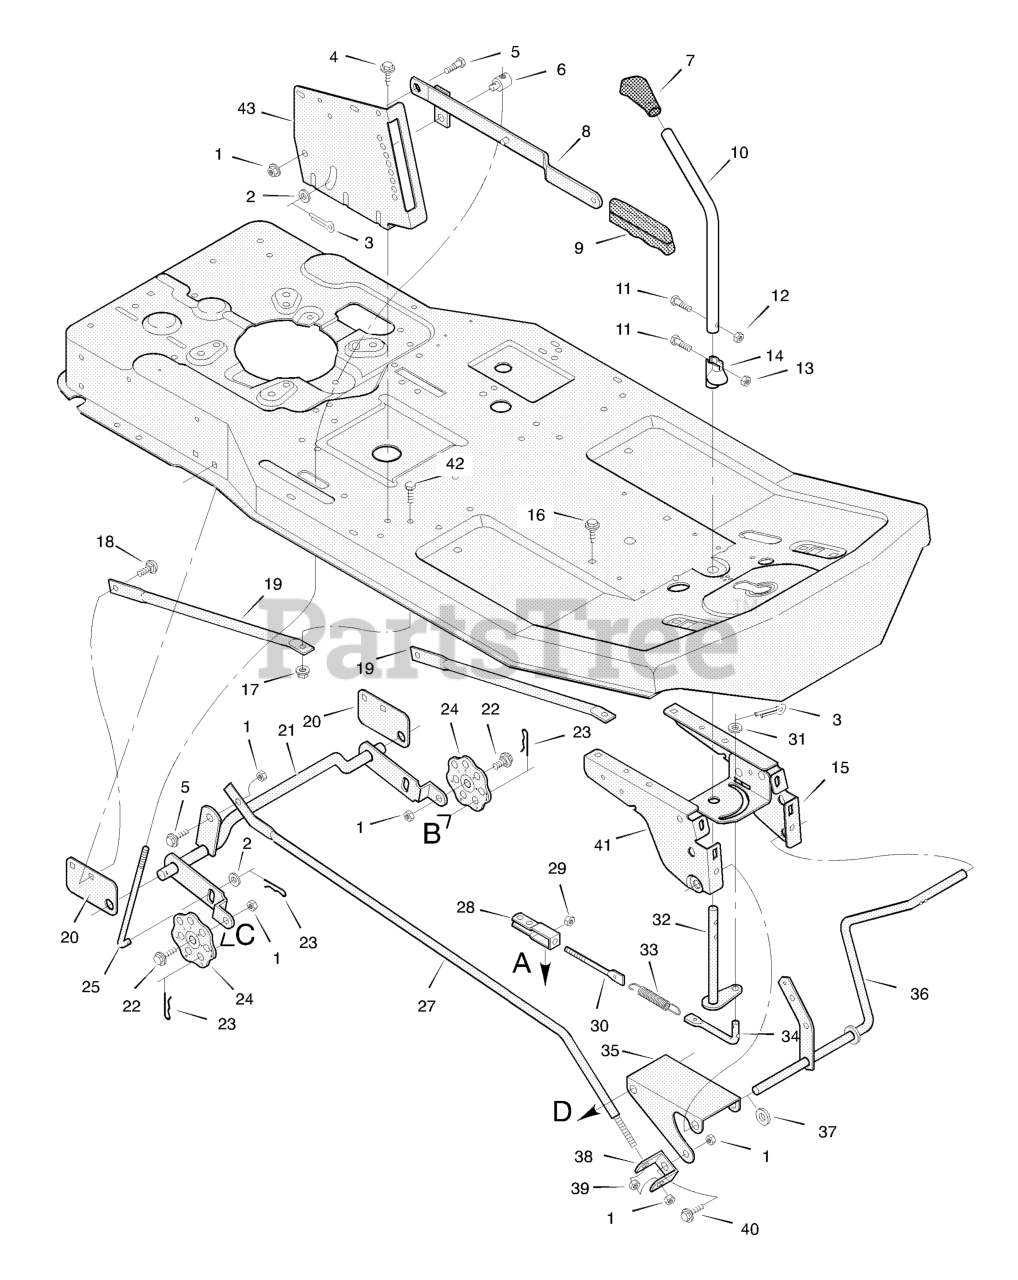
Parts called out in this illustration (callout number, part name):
1	Locknut, Flange
3	Pin, Cotter
5	Bolt, Shoulder
6	Nut, Adjusting
7	Grip, Blade Control
8	Lever Assembly, Lift
9	Grip, Lift Lever
10	Attachment, Clutch
11	Bolt, Hex
12	Locknut
13	Locknut, Flange
14	Cam, Blade Control
15	Plate, Left Suspension
17	Locknut, Flange
18	Bolt, Carriage
19	Strut, Frame
20	Plate, Mounting
21	Rod Assembly, Rear Suspension
22	Bolt, Shoulder
23	Pin, Hair
24	Plate, Adjusting
25	Rod, Lifter
27	Rod, Suspension
29	Nut, Hex
30	Link, Blade Drive
32	Rod and Arm Assembly
33	Spring, Extension
34	Link, Front Deck
35	Bracket, Front Suspension
36	Lever, Pedal
38	Clevis
39	Locknut, Hex
40	Bolt, Shoulder
41	Plate, Right Suspension
42	Bolt, Hex
43	Plate, Index
